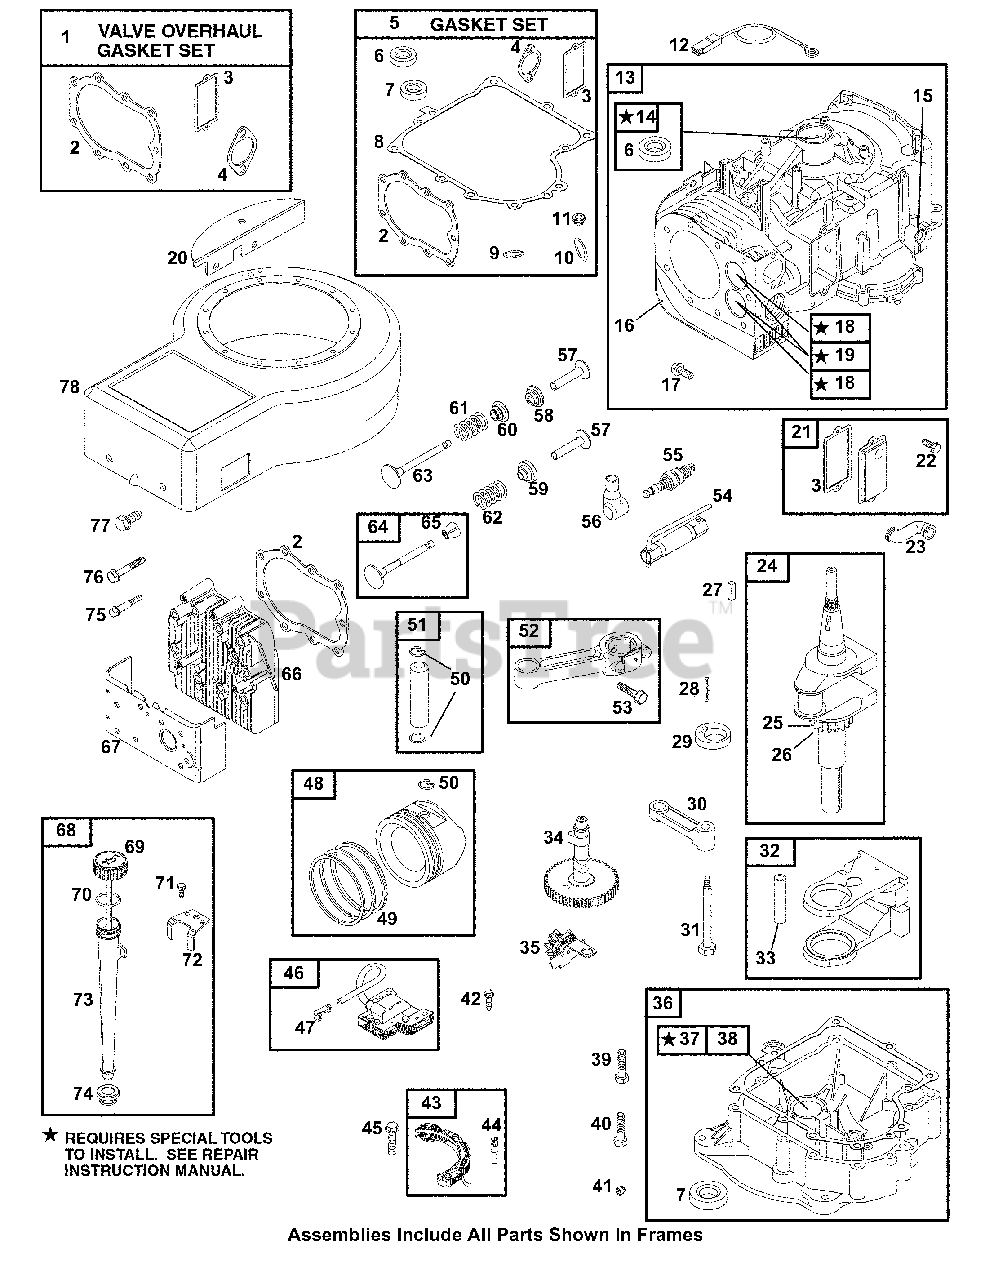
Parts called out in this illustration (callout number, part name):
1	Valve Overhaul Gasket Set
2	Cylinder Head Gasket
3	Breather Gasket
4	Intake Gasket
5	Gasket Set-Engine Overhaul
6	Oil Seal (Magneto Side)
7	Oil Seal (PTO Side)
8	Crankcase Gasket(.015" Thick)
9	O-Ring Seal (Dipstick)
10	O-Ring Seal (Air Cleaner Base)
11	Dipstick Tube Seal
13	Cylinder Assembly
14	Bushing/Seal Kit (Magneto Side)
15	Bushing-Gov. Crank
16	Shield-Cylinder
17	Screw (Cylinder Shield)
18	Seat-Valve
19	Bushing-Guide (Exhaust Valve)
20	Flywheel Guard
21	Breather Assembly
22	Screw (Breather Assembly)
23	Breather Tube
24	Crankshaft (After Code Date 98111500)
25	Gear-Timing
26	Key-Timing
27	Flywheel Key
28	Pin-Retainer
30	Link-Counterweight
31	Screw (Counterweight)
32	Counterweight
33	Pin-Counterweight
35	Governor / Oil Slinger
36	Engine Sump
37	Bushing / Seal Kit (PTO Side)
38	Oil Seal (PTO Side)
39	Screw (Engine Sump)
40	Screw (Eng Sump)
41	Oil Drain Plug
42	Screw (Magneto Armature)
43	Alternator
44	Wire-Alternator
45	Screw (Alternator)
46	Armature-Magneto
47	Terminal-Cable
48	Piston Assembly (Standard)
49	Ring Set (Standard)
50	Piston Pin Lock
51	Piston Pin (Standard)
52	Connecting Rod
53	Screw (Connecting Rod)
54	Wrench-Sparkplug
55	Spark plug
56	Boot-Sparkplug
57	Valve Tappet
58	Valve Retainer
59	Valve Retainer
60	Seal-Valve
61	Valve Spring (Exhaust)
62	Valve Spring (Intake)
63	Intake Valve
64	Exhaust Valve
65	Valve Keeper
66	Cylinder Head
67	Cover-Cylinder Head
68	Dipstick/Tube Assembly
70	O-Ring Seal (Dipstick)
71	Screw (Oil Fill Bracket)
72	Bracket-Oil Fill
73	Dipstick Tube
74	Dipstick Tube Seal
75	Screw (Cylinder Head Cover)
76	Screw (3" Long) (Cylinder Head)
77	Screw (Blower Housing)
78	Housing-Blower
